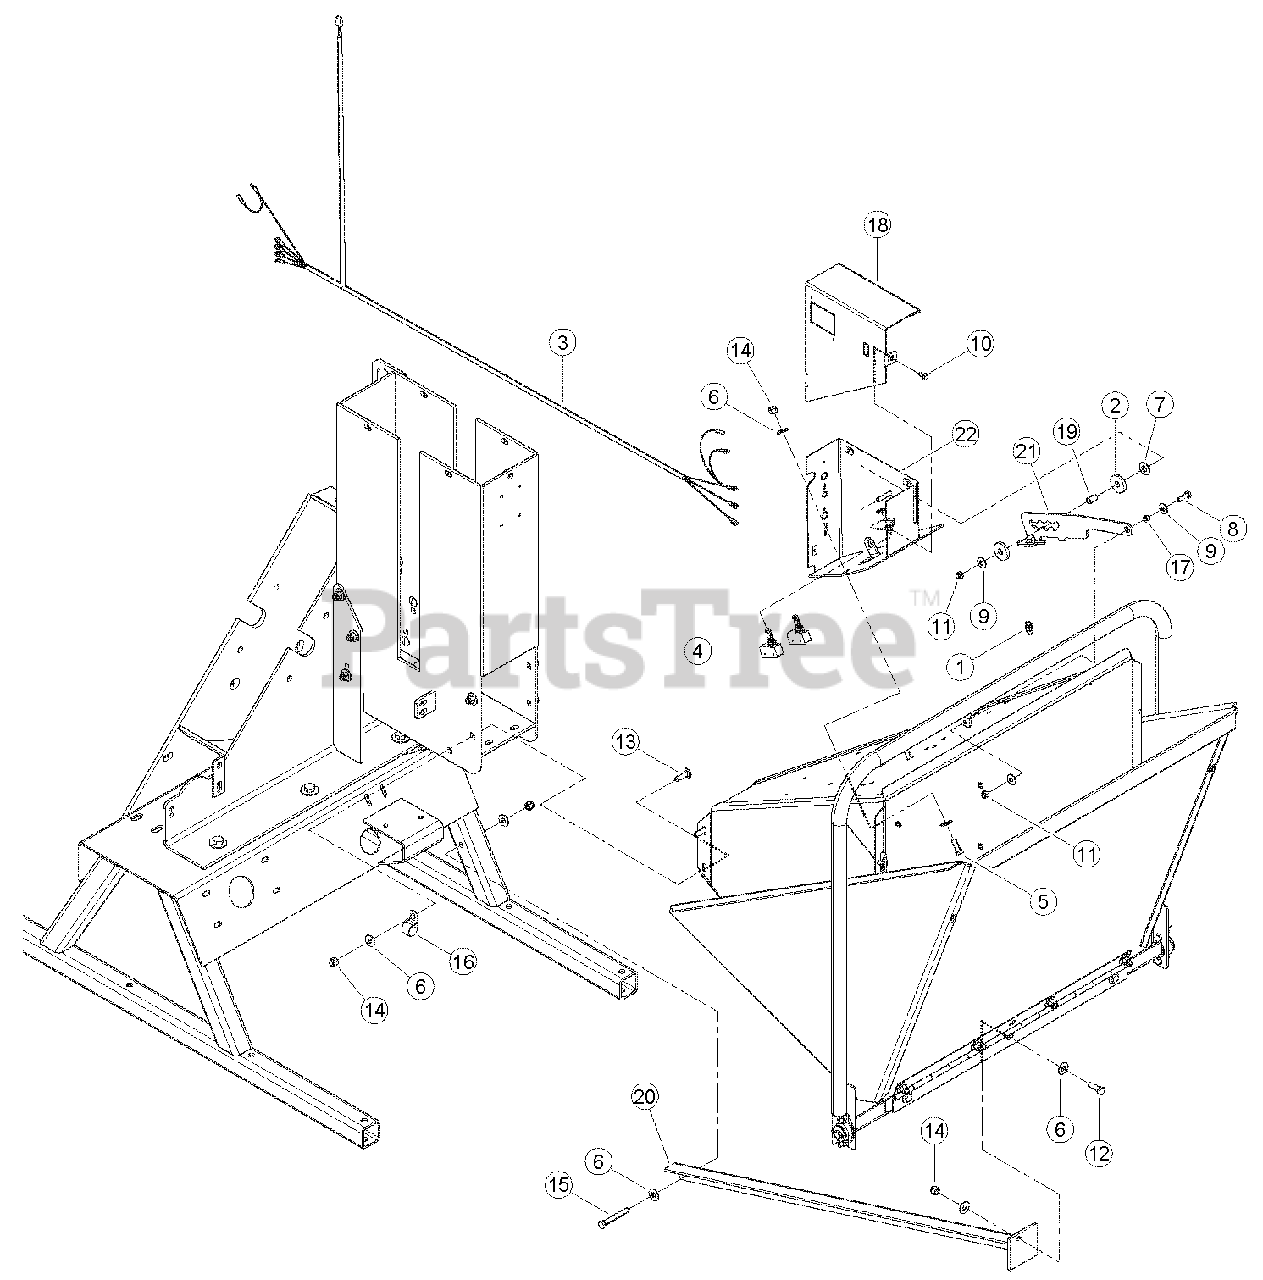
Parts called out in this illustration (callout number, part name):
1	SPRING, CONTROL BAR
2	WASHER, UHMW SPACER .515ID-1.50OD
3	HARNESS, FEED CONTROL
4	SWITCH, FEED CONTROL
5	BOLT, 3/8 X 1 HEX HD GR5 ZP
6	WASHER, 3/8" FLAT ZP (67PCS/LB)
7	WASHER 1/2"SAE FLAT ZP(56PC/LB
8	BOLT 5/16 * 1" GR5 HHCS NC ZP
9	WASHER, 5/16" FLAT ZP
10	BOLT 1/4 X 1/2" SERR FL GR5 ZP
11	NUT, 5/16" NE NYLOCK ZP
12	BOLT, 3/8 X 1-1/4 HEX HD GR5 ZP
13	BOLT, 3/8 X 1-1/4 CRG GR5 ZP
14	NUT, 3/8" NE NYLOCK ZP
15	BOLT, 3/8 X 2-3/4 HHCS GR5 ZP
16	CLAMP, 1" COATED METAL
17	SPACER, IDLER PIVOT
18	PLATE, CONTROL BOX
19	SPACER, .50 X .775
20	WELDMENT, CHUTE SUPPORT
21	BAR, SWITCH CONTROL
22	WELDMENT, SWITCH MOUNT
